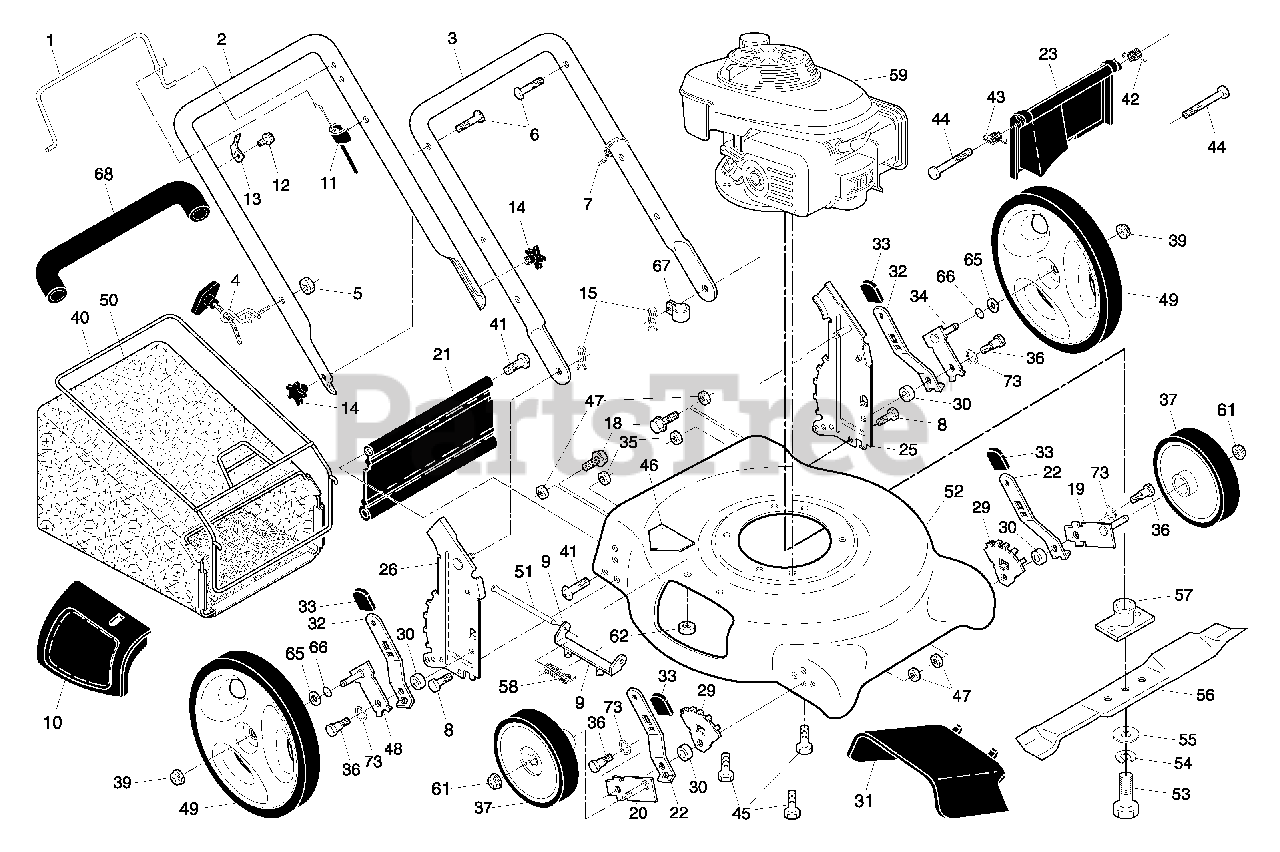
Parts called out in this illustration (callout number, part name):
1	Control Bar
2	Upper Handle
3	Lower Handle
4	Rope Guide
5	Locknut, Hex 1/4-20
6	Handle Bolt
7	Wire Tie
8	Hex Bolt 5/16-18 x 3/4
9	Hinge Bracket Assembly
10	Mulcher Door
11	Engine Zone Control Cable
12	Hex Washer Head Screw #10-24 x 1/2
13	Up-Stop Bracket
14	Handle Knob
15	Hairpin Cotter
18	Screw 1/4-20 x 3/8
19	Axle Arm Assembly, Front, LH
20	Axle Arm Assembly, Front, RH
21	Rear Skirt
22	Selector Spring, Front
23	Rear Door Assembly
24	Locknut, Hex 5/16-18
25	Handle Bracket Assembly, LH
26	Handle Bracket Assembly, RH
28	Spring, Torsion
29	Wheel Adjusting Bracket, Front
31	Discharge Deflector
32	Selector Spring, Rear
33	Selector Knob
34	Axle Arm Assembly, Rear, LH
35	Nut, Hex
36	Shoulder Bolt 5/16-18
37	Wheel & Tire Assembly, Front 8 x 1-3/4
39	Nut, Hex, Flangelock
40	Frame, Grassbag
41	Hinge Screw
42	Spring, Rear Door, LH
43	Spring, Rear Door, RH
44	Bolt, Rear Door
45	Hex Head Thread Rolling Screw 3/8-16 x 1
46	Danger Decal
47	Locknut, Hex 5/16-18
48	Axle Arm Assembly, Rear, RH
49	Wheel & Tire Assembly, Rear 12 x 1-3/4
52	Kit, Lawn Mower Housing Assembly
53	Hex Head Screw 3/8-24 x 1-3/8 Grade 8
54	Helical Lockwasher
55	Hardened Washer
56	21" Blade
57	Blade Adapter
61	Nut, Hex, Flangelock
62	Nut, Hex, Nylock 1/4-20
65	Washer, Flat
67	Clip, Cable
68	Grip, Foam
73	Washer, Flat
74	Washer, Special, Engine
